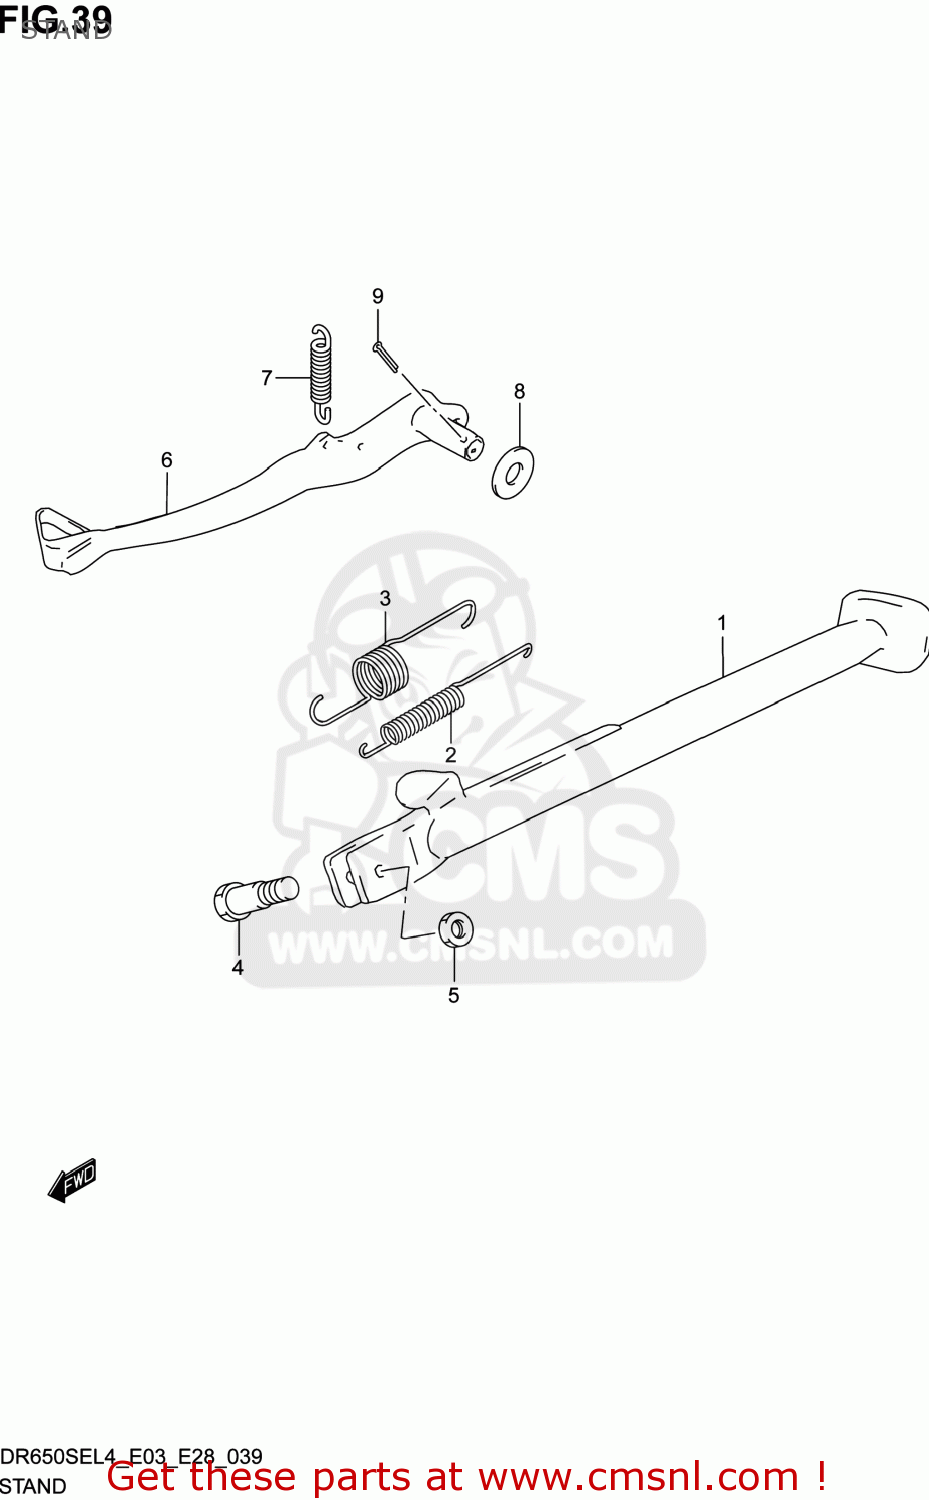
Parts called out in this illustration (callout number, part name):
1	STAND,PROP
2	SPRING
3	SPRING
4	BOLT(10X30)
5	NUT
6	PEDAL,BRAKE
7	SPRING
8	WASHER(15.5X24X2.3)
9	PIN
